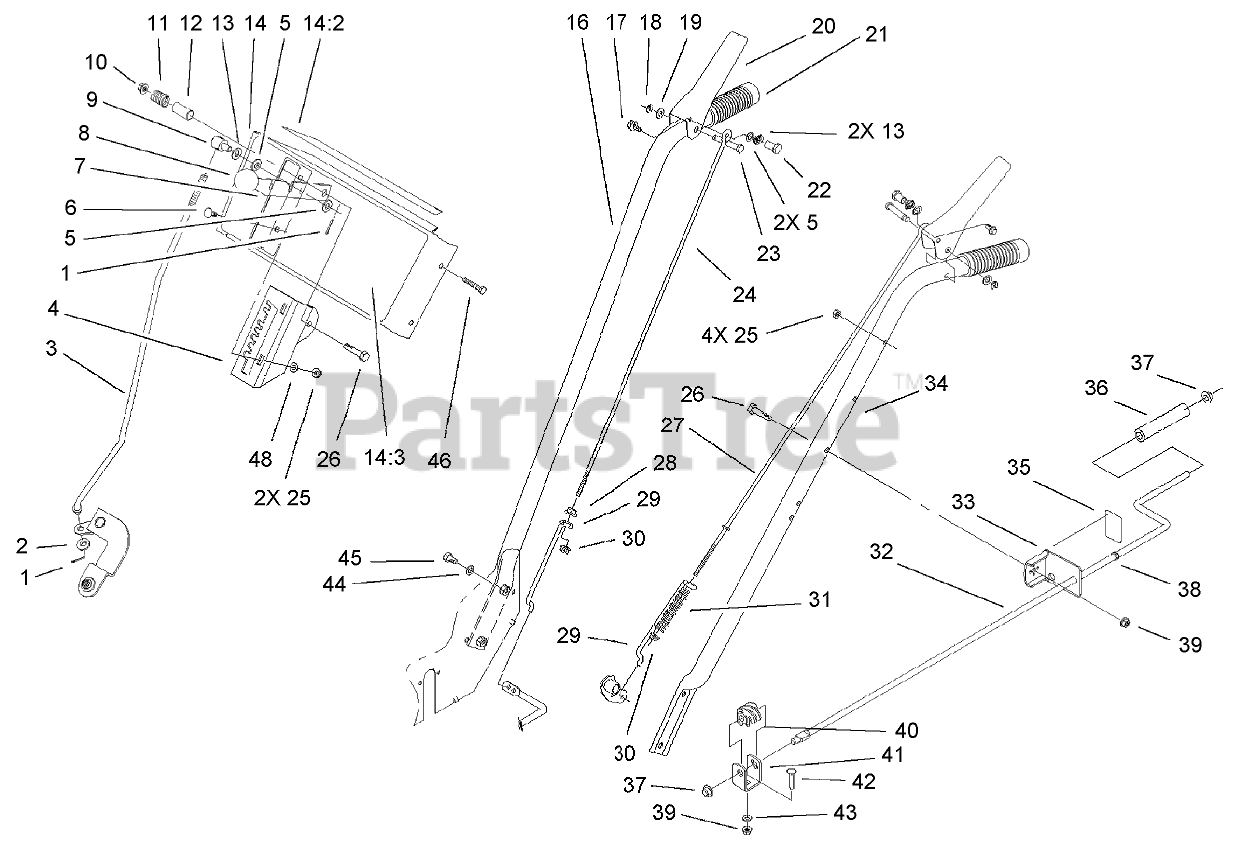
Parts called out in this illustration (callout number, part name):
1	PIN-COTTER
2	WASHER-FLAT
3	ROD-SHIFT
4	MOUNT-SPEED SELECTOR
5	WASHER-FLAT
6	SCREW-CARR
7	SELECTOR-SPEED
9	TRUNNION
10	NUT-HF
11	SPRING
12	SPACER
13	WASHER-SPRING
14	CONTROL PANEL ASM (only on: 38078)
14	CONTROL PANEL ASM (only on: 38053)
14:2	DECAL-ESCUTCHEON BACK (only on: 38078)
14:2	DECAL-ESCUTCHEON BACK (only on: 38053)
14:3	DECAL-CONTROL PANEL (only on: 38053)
14:3	DECAL-CONTROL PANEL (only on: 38078)
16	HANDLE-RIGHT
17	SCREW-HHF
18	RING-CLIP
19	WASHER-PLAIN
20	HANDLE-CONTROL
21	GRIP-HANDLE
22	POST-MOUNTING, LINKAGE
23	PIN-LEVER, CONTROL
24	ROD-UPPER ENGAGE AUGER
25	NUT-LOCK, NI
26	SCREW-HH
27	ROD-UPPER TRACTION
28	NUT-HF
29	ROD-LOWER TRACTION
30	NUT-HHF
31	SPRING
32	ROD-CONTROL, CHUTE
33	BRACKET-ROD, CHUTE
34	LEFT HANDLE
35	DECAL-CHUTE DIRECTION
36	GRIP-CONTROL, CHUTE
37	RETAINER-PUSH ON
38	Bushing
39	NUT-LOCK, NI
40	GEAR-WORM, CHUTE
41	BRACKET-WORM
42	SCREW-CARR
43	WASHER-LOCK
44	WASHER-BELLEVILLE
45	SCREW-HWHTF
46	SCREW-HH
48	WASHER-FLAT
